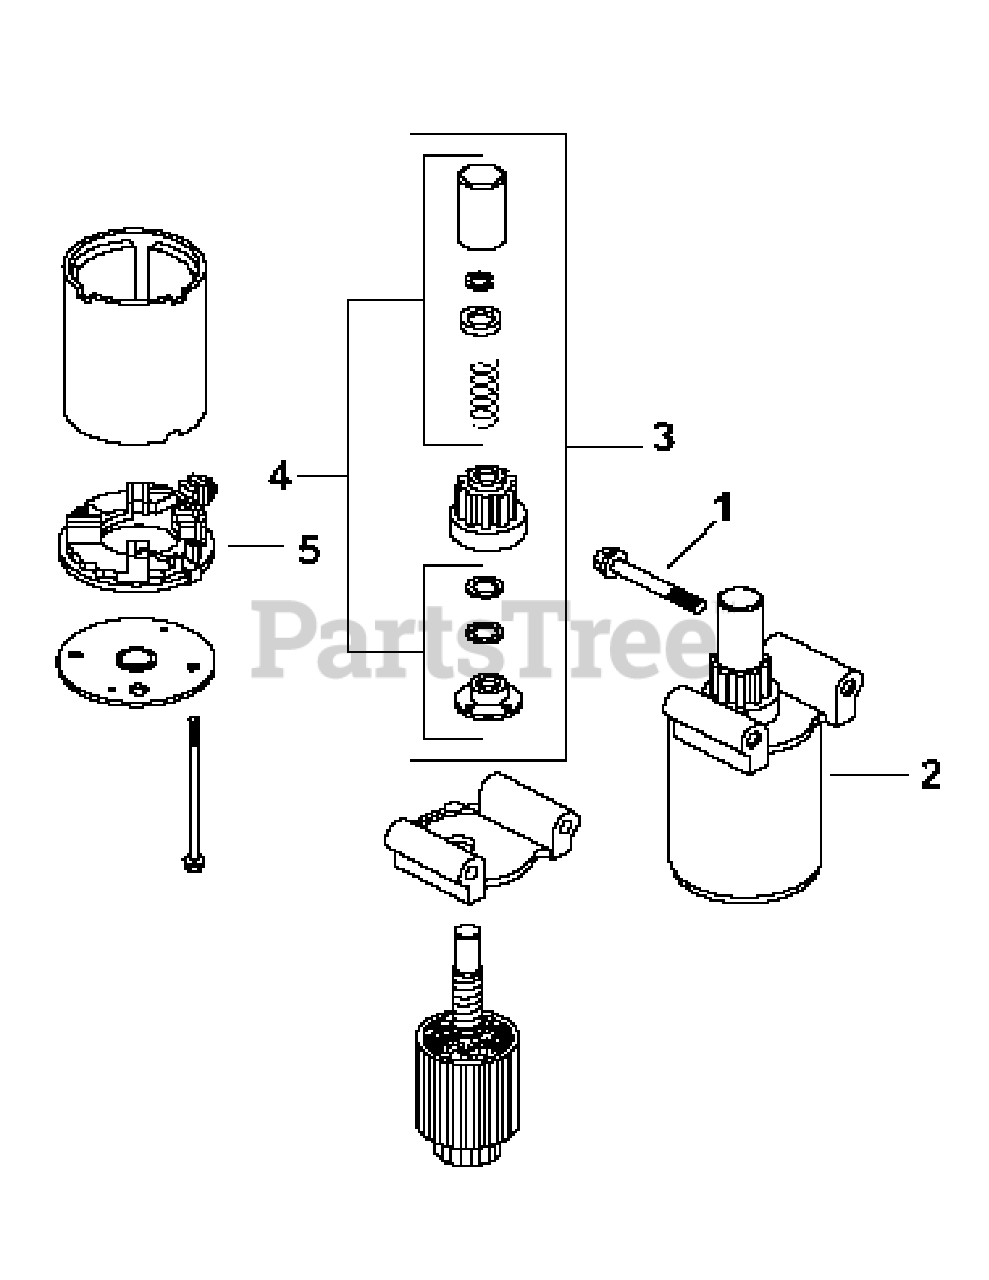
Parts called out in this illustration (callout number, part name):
1	Hex Flange Screw (M8 x 1.25 x 80)
2	Starter Assembly
4	Drive Parts kit
5	End Cap Commutator
